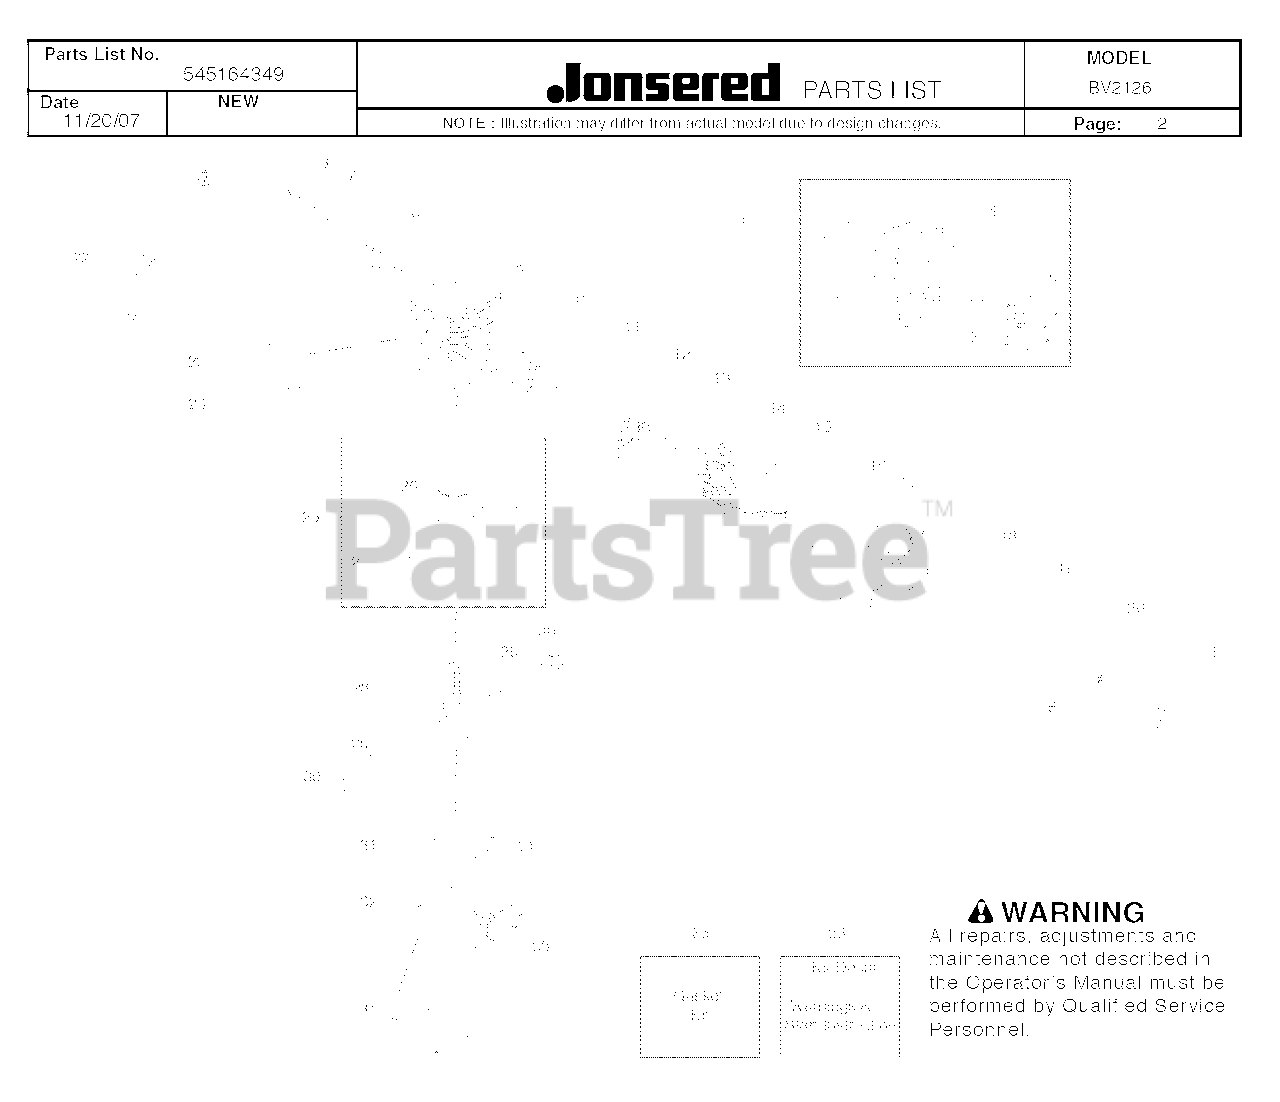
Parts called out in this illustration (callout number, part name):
1	ASSY, MUFFLER
3	KIT, SPARK SCREEN
4	BOLT MUFFLER
5	SCREW-6-19X5/16PLAST PA
6	KIT SWITCH
7	PROTECTOR, SWITCH
8	PLUG-SPARK (RCJ-6Y)
9	CYLINDER -CHROME
10	BOOT, CARB
12	PLATE, CARB
14	KIT, CARB
15	AIR PURGE
17	BASE - AIR BOX
19	FILTER, AIR
20	COVER - AIR BOX
21	ASSY - AIR BOX KNOB
22	ASSY, LEADWIRE
23	IGNITION MODULE
24	SCREW M4 X .70 TT 16MM
25	KIT - PISTON
26	RING PISTON
27	WRIST PIN RET.
28	KIT, CRANKSHAFT
29	BEARING RADIAL BALL (6201)
30	CRANKSHAFT SEAL
32	CAP - BEARING
34	B0LT, C/SHAFT 36/41
